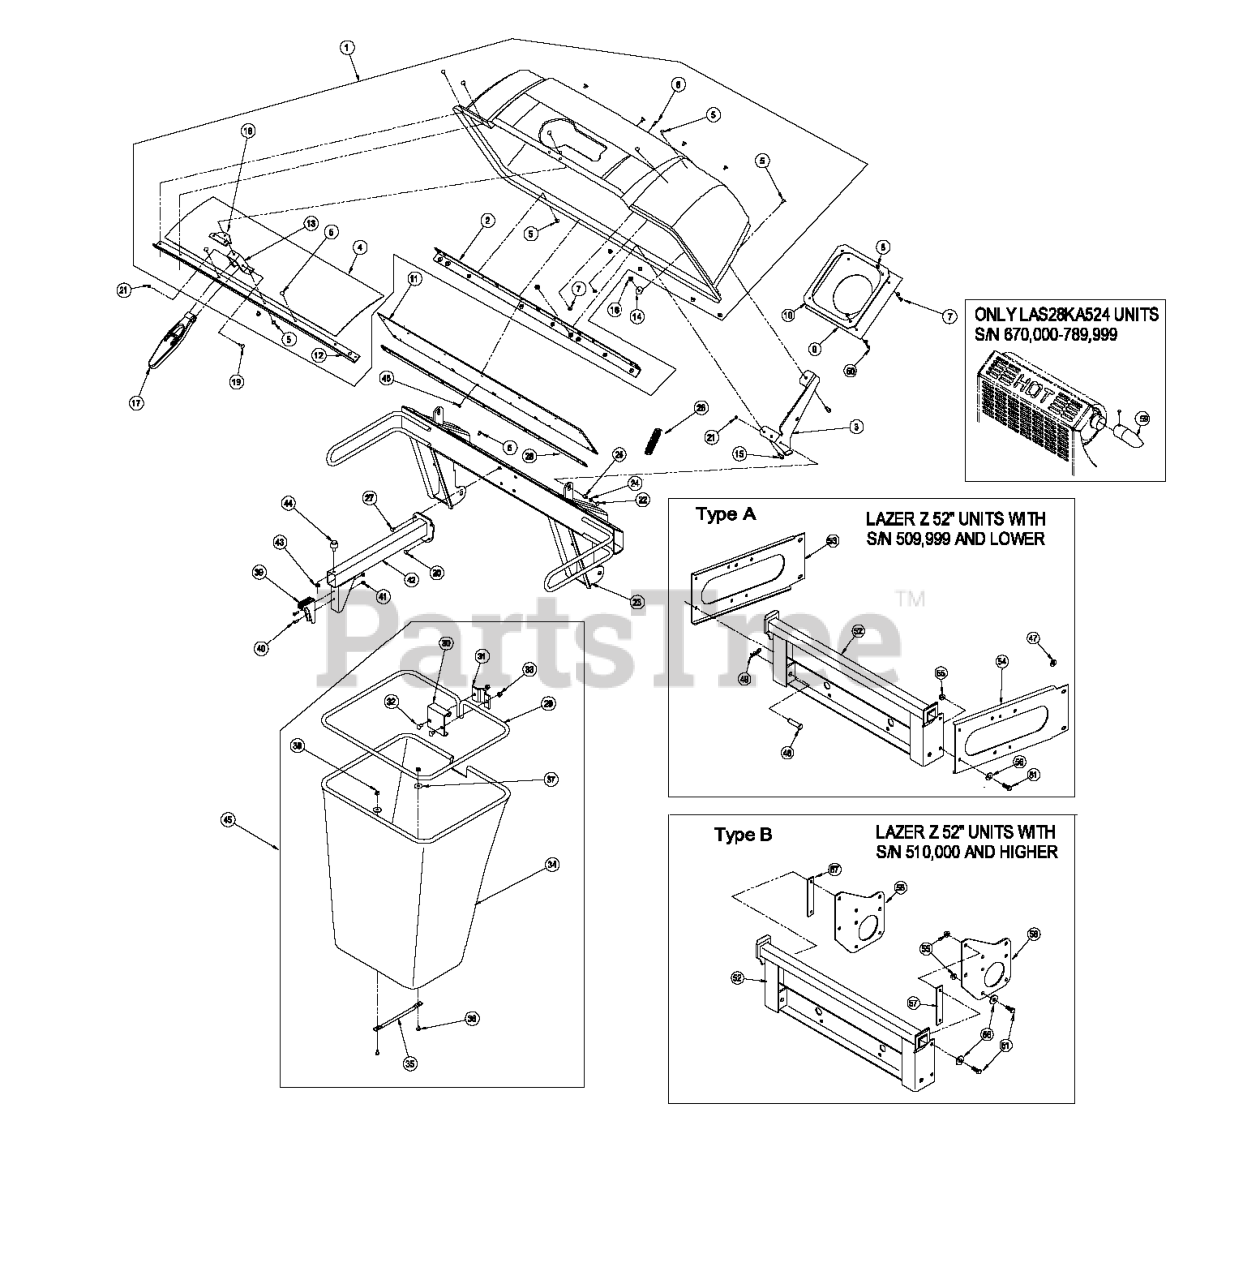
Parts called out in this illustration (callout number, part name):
1	Asm, Hood
2	Stiffener, Bagger Top
3	Wld, Hinge (RH)
3	Wld, Hinge (LH)
4	Screen
5	Rivet, Pop 3/16 x 1/2
6	Screw, Truss HD #10-24 x 3/4
7	Washer, 216 x 750 x 049
8	Nut, Nyloc #10-24
9	Seal, Chute
10	Clamp, Seal
12	Support, Screen
13	Mount, Latch
14	Washer, 344 x 175 x 062 Pltd
15	Screw, HH 1/4-20 x 3/4
16	Nut, Whizlock 1/4-20
18	Reinforcement, Latch
19	Screw, HH 1/4-20 x 2
20	Screw, HSBH 5/16-18 x 3/4
21	Nut, Nyloc 1/4-20
22	Screw, HH 1/4-20 x 1
23	Wld, Bagger Upright
24	Washer, 1/4 Std
27	Screw, HH 5/16-18 x 3/4
28	Plate, Backing
29	Frame, Bag
30	Hanger, Bag
32	Bolt, Carriage 5/16-18 x 3/4
33	Nut, Nyloc 5/16-18
34	Bag, Cloth
35	Handle, Bag
36	Bolt, Carriage 1/4-20 x 3/4
37	Washer, 344 x 175 x 062 Pltd
38	Nut, Nyloc 1/4-20
40	Screw, PPH #10-24 x 5/8
41	Nut, Whizlock #10-24
42	Wld, Bag Support
43	Nut, Whizlock 1/4-20
45	Asm, Bag
46	Nut, Side Lock #10-24
47	Spacer, ROPS (Type A)
48	Clevis Pin
49	Hairpin, Cotter
50	Screw, PPH #10-24 x 7/8
51	Screw, HH 3/8-16 x 1 1/4 (Type A)
52	Wld, Bagger Mount
53	Frame, Bracket (LH) (Type A)
54	Frame, Bracket (RH) (Type B)
55	Nut, Whizlock 3/8-16 (Type A)
55	Nut, Whizlock 3/8-16 (Type B)
56	Washer, Spring Disc 3/8 (Type A)
56	Washer, Spring Disc 3/8 (Type B)
57	Spacer (Type B)
58	Plate, Bagger Mount (Type B)
59	Diverter, Muffler W/Screw
